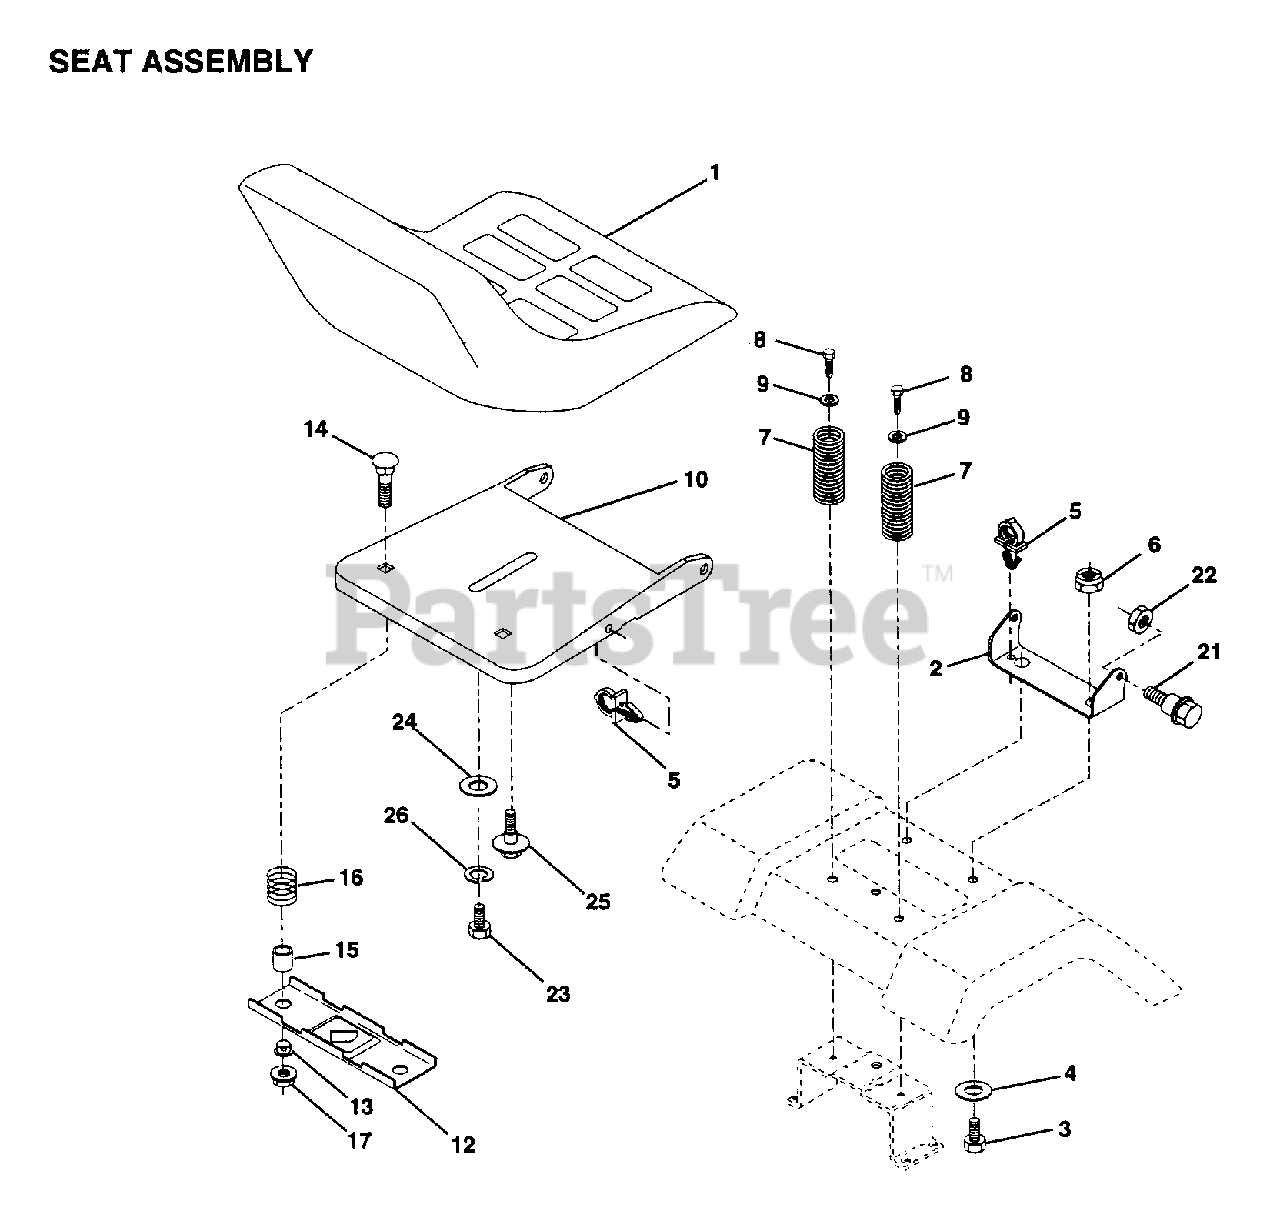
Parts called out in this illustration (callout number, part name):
2	BRACKET PVT SEAT
3	BOLT
4	WASHER PM
5	CLIP.PUSH-IN.HING
6	NUT
7	SPRING COMPRESSIO
8	SCREW GTV
9	WASHER
12	BRKT SWITCH
13	BUSHING
15	SPLIT SPACER
16	SPRING
21	BOLT.SHLD.5/16-18
22	NUT
23	BOLT
24	WASHER
25	"BOLT,SHOULDER"
26	LOCKWASHER
